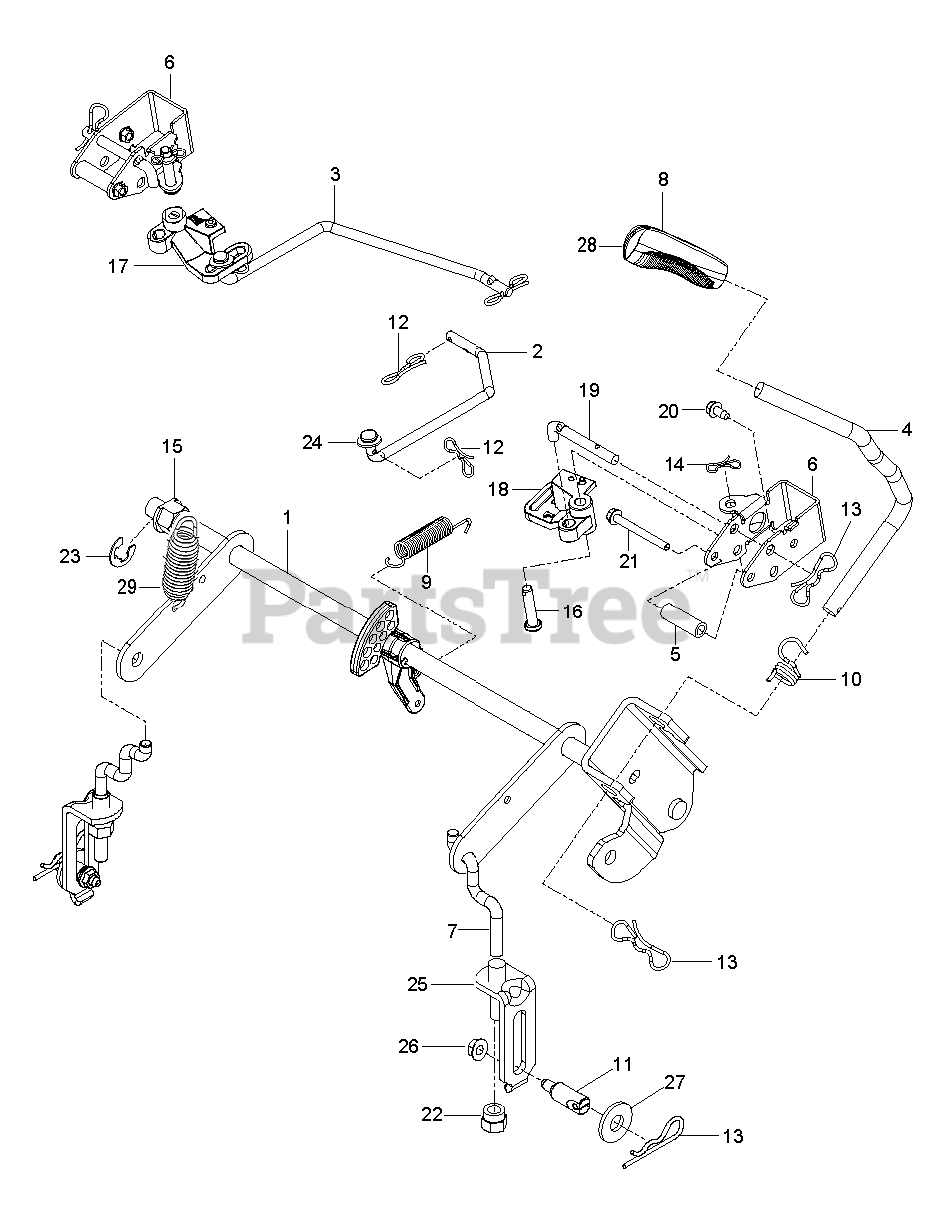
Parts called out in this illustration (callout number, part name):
1	SHAFT ASSY DECK LIFT WELDMENT
1	SHAFT.ASM.RZ.DECK.LIFT.SRV
2	LINK.BRAKE.PARK.UPPER.LH
3	LINK.BRAKE.PARK.UPPER.RH
4	LIFT.LEVER.ASM.RZ.SERVICE
4	HANDLE LIFT ZTR
5	SPACER.334.ID.5.OD.1.5.L
6	BRACKET.BELLCRANK.PBRAKE X431
7	LINK, REAR SUSPENSION
8	GRIP.HANDLE.LIFT.PVC.BLACK
9	RETURN.BRAKE.PARK.AUTO
10	SPRING.TORSION.LIFT.HANDLE
11	STUD.FASTNER.W/ANTI-ROTATE
12	PIN COTTER;LOCKING;BOWTIE;1IN
13	PIN.COTTER.7/16.BOW TI.
13	SPRING.TORSION.LIFT.HANDLE
14	PIN.COTTER.5/16.BOW TI
14	PIN COTTER;LOCKING;BOWTIE;1IN
15	PLASTIC NUT
16	PIN.5.16X1.5
17	BELLCRANK.RH
18	BELLCRANK.LH
19	ROD.PUSH.BRAKE
20	SCREW.1/4-20X5/8
21	SCREW THD;ROLL;1/4-20 X 2.25
22	NUT, LIFT LINK 7/16-20
23	RETAINING RING LT
24	WASHER
25	ASSEMBLY, BRKT LINK
25	LINK.ASM.RZ.LIFT.SERVICE
26	5/16-18 NYLOC FLANGE NUT
27	WASHER
28	GRIP.HANDLE.LIFT.PVC.428
29	SPRING
